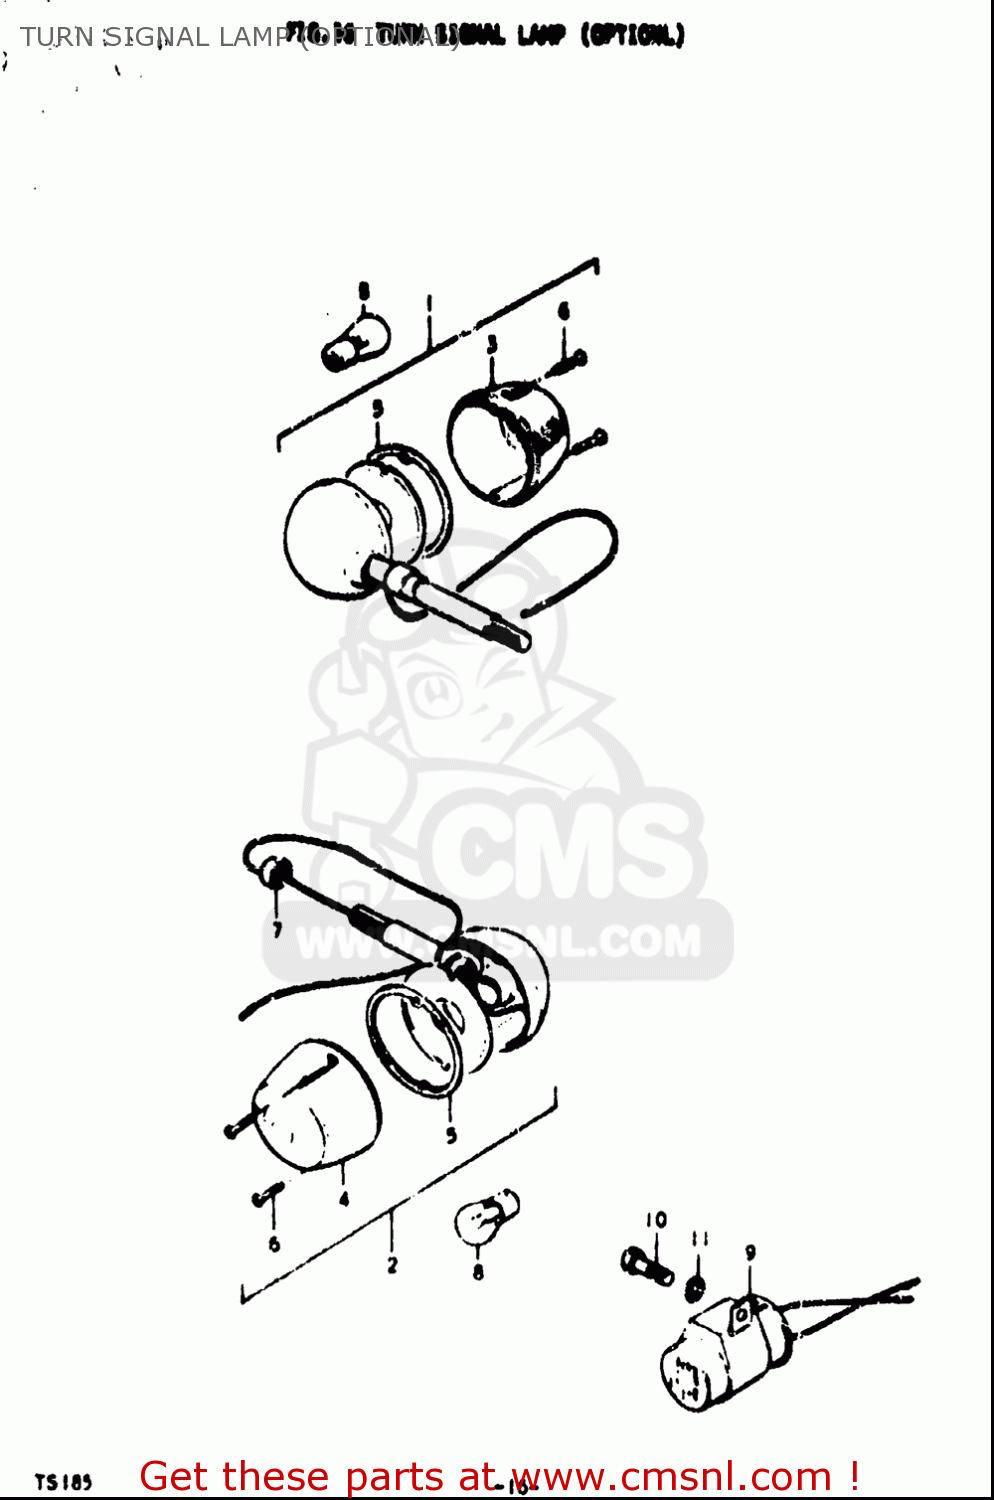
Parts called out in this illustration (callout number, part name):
3	LENS,TURNSIGNAL
4	LENS,RR TURNSIGNAL LAMP
5	GASKET,TURNSIGNAL LENS (NAS)
6	SCREW
7	NUT
8	BULB(6V17W,STANLEY,A4513A)
9	RELAY ASSY,TURNSIGNAL
10	BOLT
11	WASHER,LOCK
